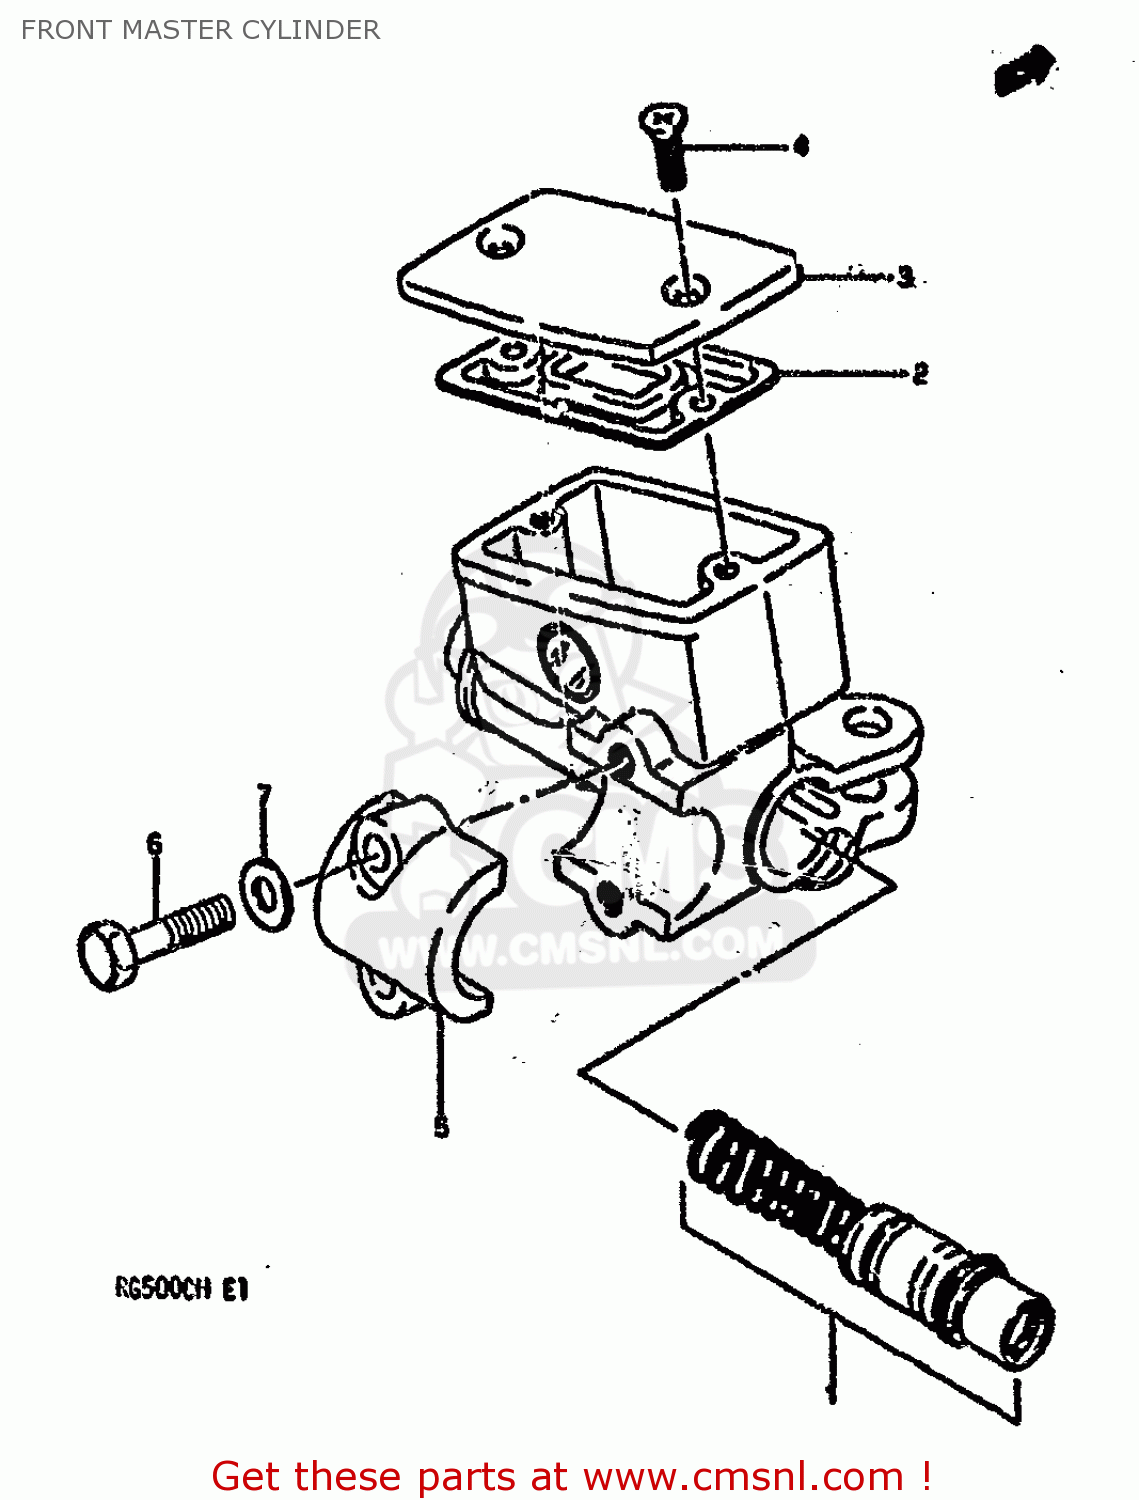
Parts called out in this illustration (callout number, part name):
1	PISTON & CUP SET
2	DIAPHRAGM
3	CAP
4	SCREW
5	HOLDER,MASTER CYLINDER
6	BOLT
7	WASHER
